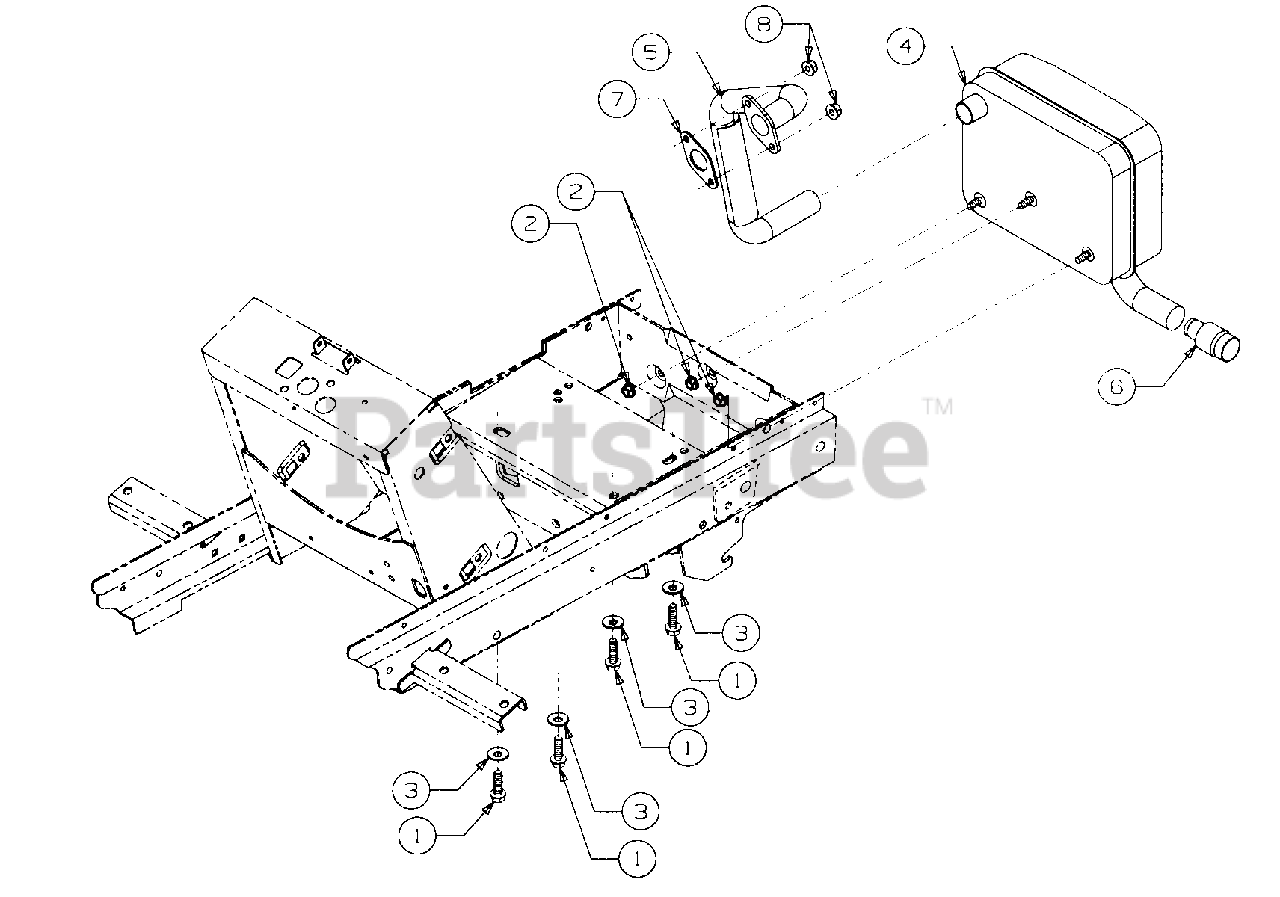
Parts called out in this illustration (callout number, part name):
1	Bolt, Engine Mtg, 3/8-16 x 1.25 Lg
2	Nut, Hex Flange Top Lock, 5/16-18
3	Washer, Bell, .380 x .88 x .062 Thk
4	Muffler Assy w/Shields
5	Tube, Exhaust
6	Arrestor, Spark
7	Gasket, Exhaust
8	Nut, Hex Flange
